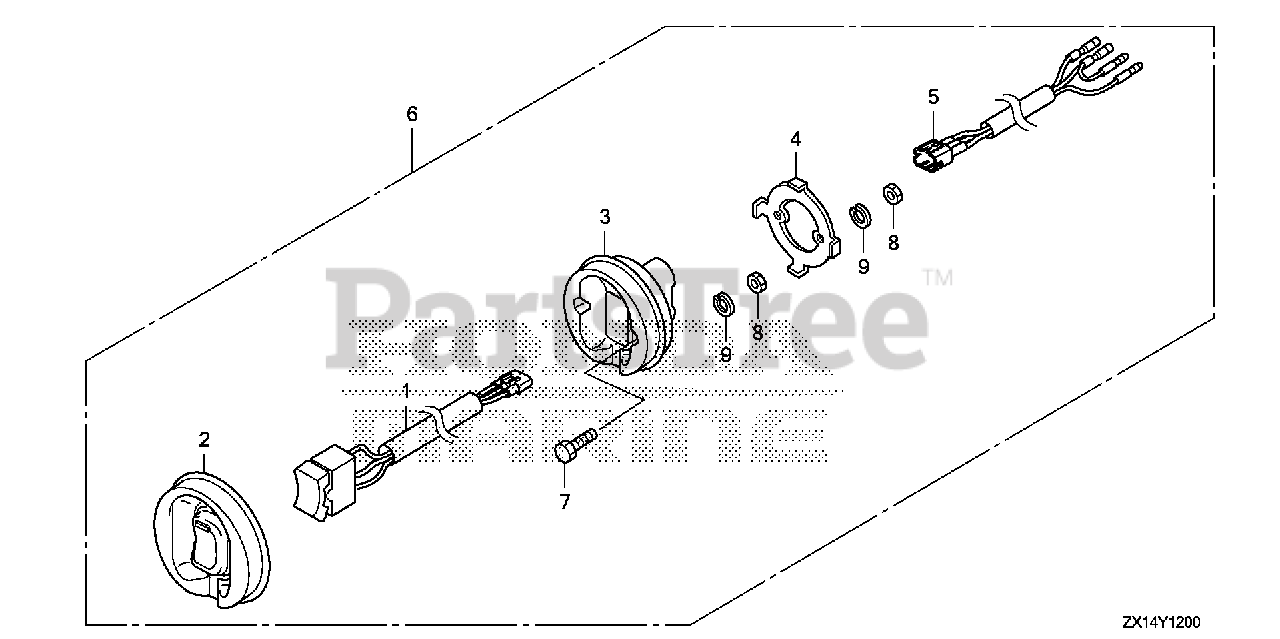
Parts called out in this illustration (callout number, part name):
1	SWITCH ASSY., TROLLING CONTROL
2	RUBBER, TROLLING CONTROL SWITCH PANEL
3	BODY, TROLLING CONTROL SWITCH PANEL
4	BRACKET, TROLLING CONTROL SWITCH PANEL
5	HARNESS, TROLLING CONTROL SWITCH PANEL
6	PANEL ASSY., TROLLING CONTROL
7	BOLT, HEX. (4X20)
8	NUT, HEX. (4MM) (NOT AVAILABLE)
9	WASHER, SPRING (4MM)
